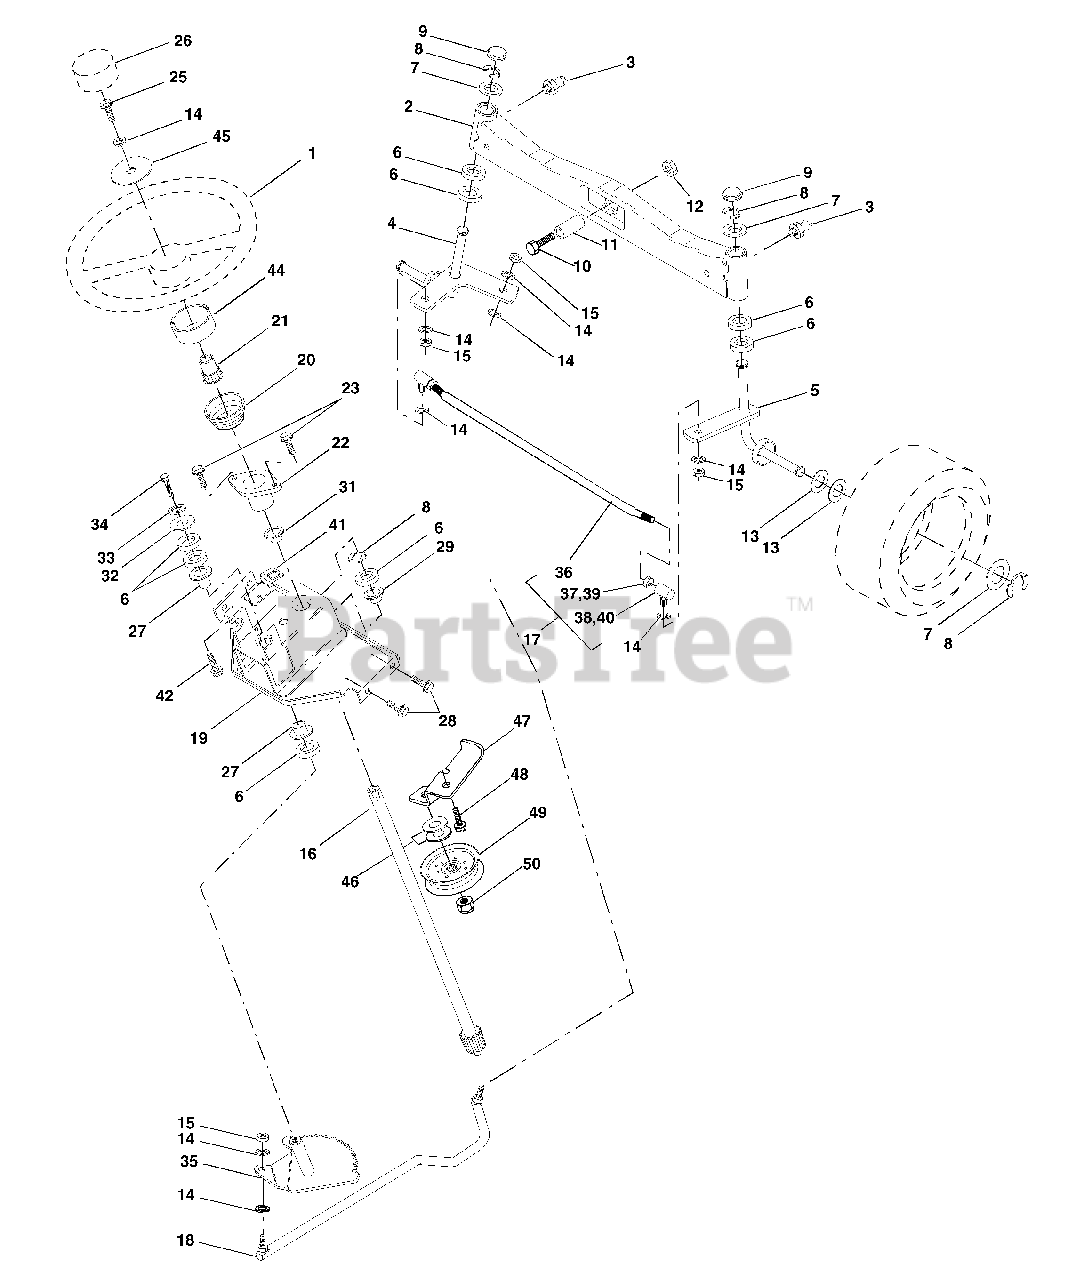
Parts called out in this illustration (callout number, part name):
1	Wheel, Steering
2	Axle Asm., Front
3	Fitting, Grease
4	Spindle Asm, LH
5	Spindle Asm., RH
6	Bearing, Race Thrust Harden
7	Washer 25/32 x 1-5/8 x 16 Ga.
8	Ring, Klip #T5304-75
9	Cap, Spindle
10	Bolt, Fin Hex 5/8-11 x 2-3/4
11	Spacer, Brg. Axle Front
12	Nut, Lock Flange 5/8-11 Unc
13	Washer 25/32 x 1-1/4 x 16 Ga.
14	Washer, Lock Hvy Hlcl Spr 3/8
15	Nut Lock Center 3/8-24 Unf
16	Shaft Asm., Steering
17	Rd Asm. Tie Ball
18	Draglink, Ball Joint Solid Vgt
19	Support Asm., Steering Vgt
20	Boot Steering Stealth
21	Adapter, Wheel Steering
22	Bushing, Strg.
23	Screw
25	Bolt, Fin Hex 3/8-16 x 1 Gr. 5
26	Insert Cap Strg WH
27	Bearing, Col. Strg.
28	Screw Hexwsh thdr 3/8-16 x 3/4
29	Bearing, Flange
31	Bushing, Nyliner Snap
32	Washer 11/32 x 1 x 10 Ga.
33	Washer, Lock Hvy Hlcl Spr 5/16
34	Bolt, Hex Hd 5/16-18 x 3/4
35	Gear, Sector Steering
36	Tie Rod
37	Nut Hex Jam 3/8-24 Unf
38	Joint Asm. Ball RH Service
39	Nut Hex Jam 3/8-24 Unf LH
40	Joint Asm. Ball LH Service
41	Bracket Switch Interlock Vgt 97
42	Screw Thdrol 5/16-18 x 1/2 Tyt
44	Extension Steering
45	Washer 13/32 x 1-1/2 x 11 Ga.
46	Washer 13/32 x 1 x 10 Ga.
47	Bracket Asm. Idler Stationary
48	Screw 3/8-16 x .75
49	Pulley Idler Flat
50	Nut Lock Flg. 3/8-16 Unc
